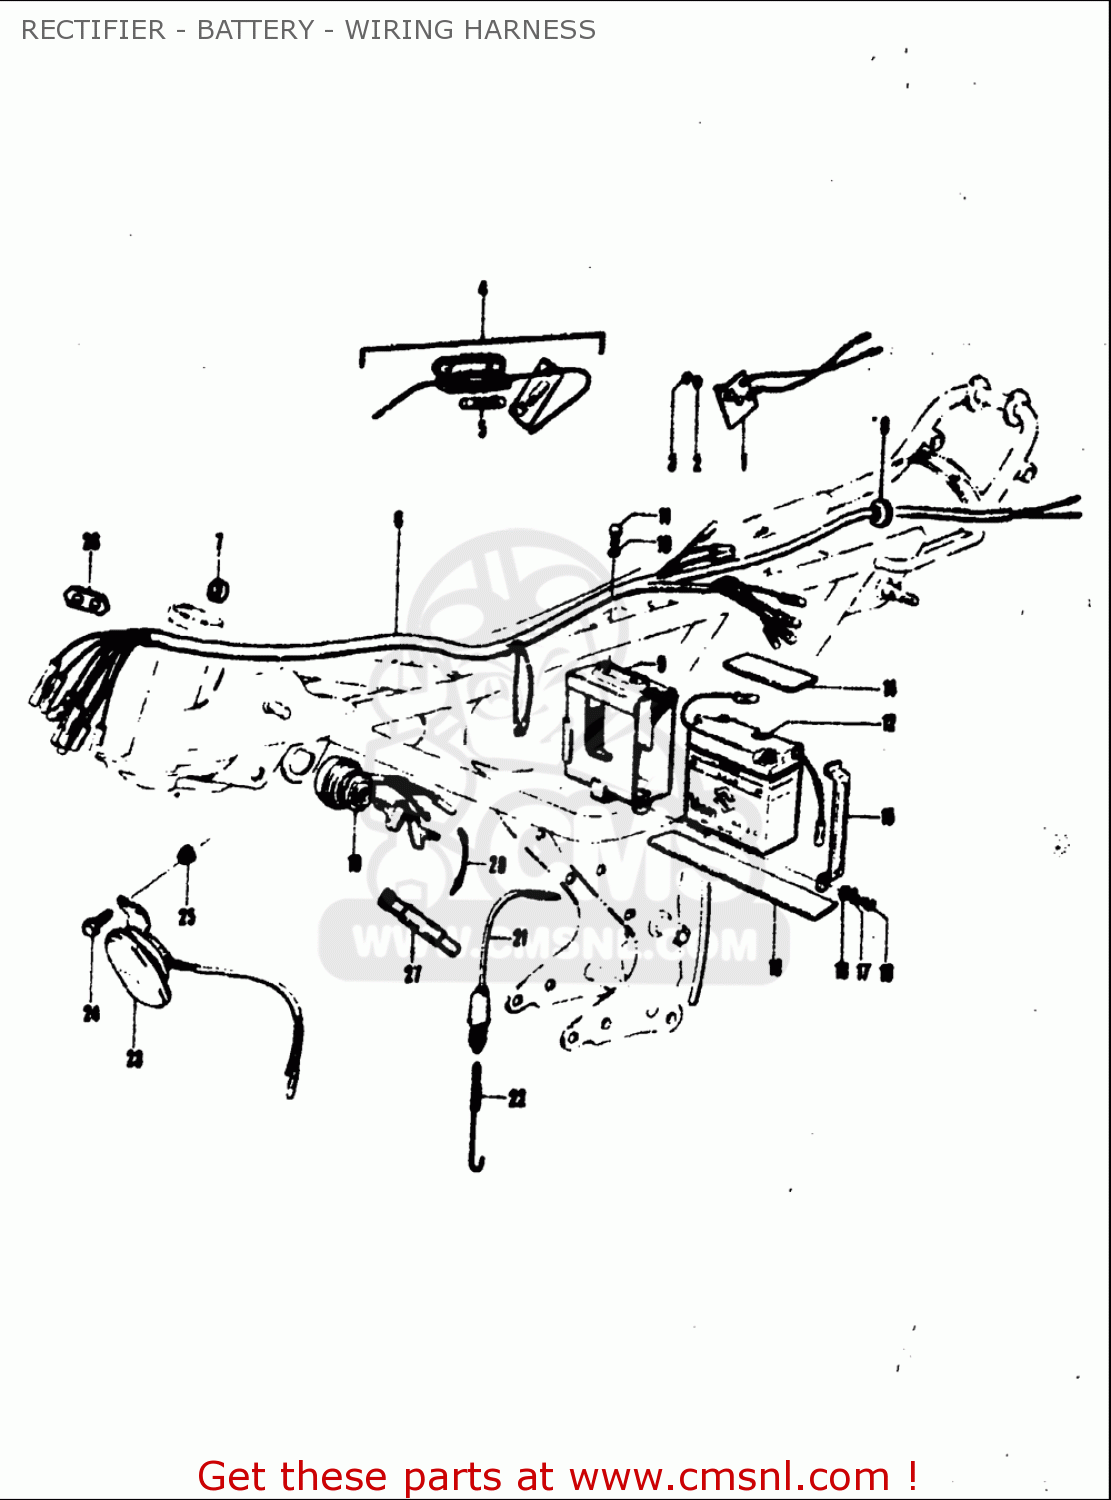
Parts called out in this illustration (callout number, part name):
2	WASHER,LOCK
3	NUT
4	CASE ASSY,FUSE
5	FUSE(15A)
10	WASHER,LOCK
12	BATTERY(6N4B-2A,6V4.2AH)
16	WASHER
17	WASHER,LOCK
18	SCREW(6X10)
20	LEAD WIRE
21	SWITCH,BRAKE LAMP
23	HORN ASSY
25	WASHER
